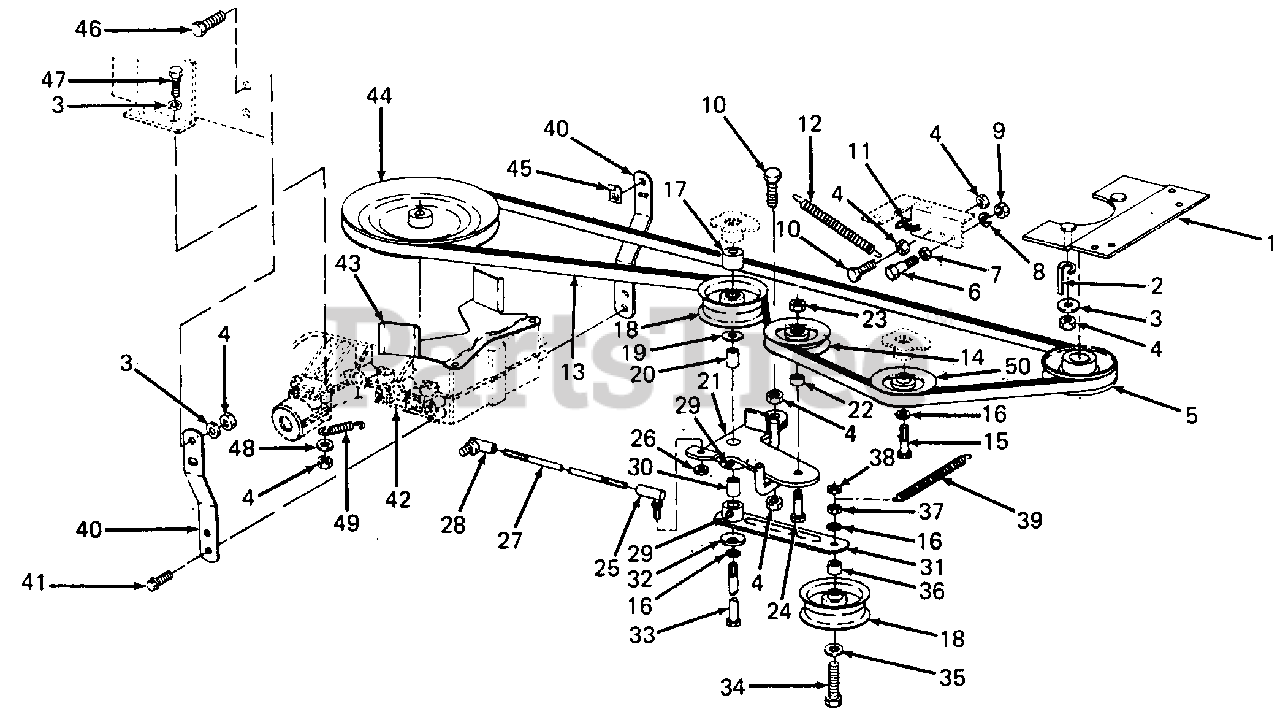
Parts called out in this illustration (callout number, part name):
1	Plate, Belt Guard Mounting
2	Guide, Belt
3	Washer, Bell, .345 X .88 X .060 Thk
4	Nut, Hex Center Lock, 5/16-18 GR5
5	Pulley, Engine, 3.5 OD
6	Screw, Shoulder
7	Nut, Hex Jam, 5/16-18 GR5
8	Washer, Lock, 5/16
9	Nut, Hex, 5/16-18 GR5
10	Screw, Hex Cap, 5/16-18 X 1.0 Lg GR5
11	Tie, Cable
12	Spring, Extension, .62 OD X 6.12 Lg
13	V-Belt, 1/2 X 91.0 Lg
14	V-Idler, 3.06 OD
15	Screw, Hex Cap, 3/8-16 X 1.25 Lg GR5
16	Washer, Lock, 3/8
17	Bushing, .390 X 1.0 X .812 Lg
18	Pulley, Flat Idler, 2.75 OD
19	Washer, Flat, .385 X .87 X .06 Thk (Hdn)
20	Spacer, .380 X .625 X 1.14 Lg
21	Bracket, Clutch
22	Spacer, .380 X .625 X .27 Lg
23	Nut, Hex Center Lock, 3/8-16 GR5
24	Screw, Hex Cap, 3/8-16 X 1.75 Lg GR5
25	Joint, Ball, 5/16-24 RH Trd
26	Nut, Hex, 5/16-24 GR5
27	Rod, Clutch
28	Joint, Ball, 5/16-24 LH Trd
29	Fitting, Lube, 3/16 Drive
30	Spacer, .377 X .600 X .830 Lg
32	Washer, Flat, .406 X 1.25 X .157 Thk (Hdn)
33	Screw, Hex Cap, 3/8-16 X 4.75 Lg GR5
34	Screw, Hex Cap, 3/8-16 X 2.75 Lg GR5
35	Washer, Flat, .385 X .620 X .063 Thk
36	Spacer, .375 X .625 X .44 Lg
37	Nut, Hex Jam, 3/8-16 GR5
38	Nut, Hex Center Lock Jam
39	Spring, Extension, .41 OD X 6.0 Lg
40	Brace, Transmission
41	Screw, Hex Wash Hd Tapp, 5/16-18 X .62 Lg
42	Transmission - 5 Speed
43	Belt Keeper, Transaxle
44	Pulley, Transmission
45	Clip, Cable
46	Screw, Hex Cap, 5/16-18 X .75 Lg GR5
47	Screw, Hex Cap, 5/16-18 X 2.5 Lg GR5
48	Washer, Flat, .344 X .875 X .06 Thk
49	Spring, Extension
50	V-Idler, 2.62 OD
